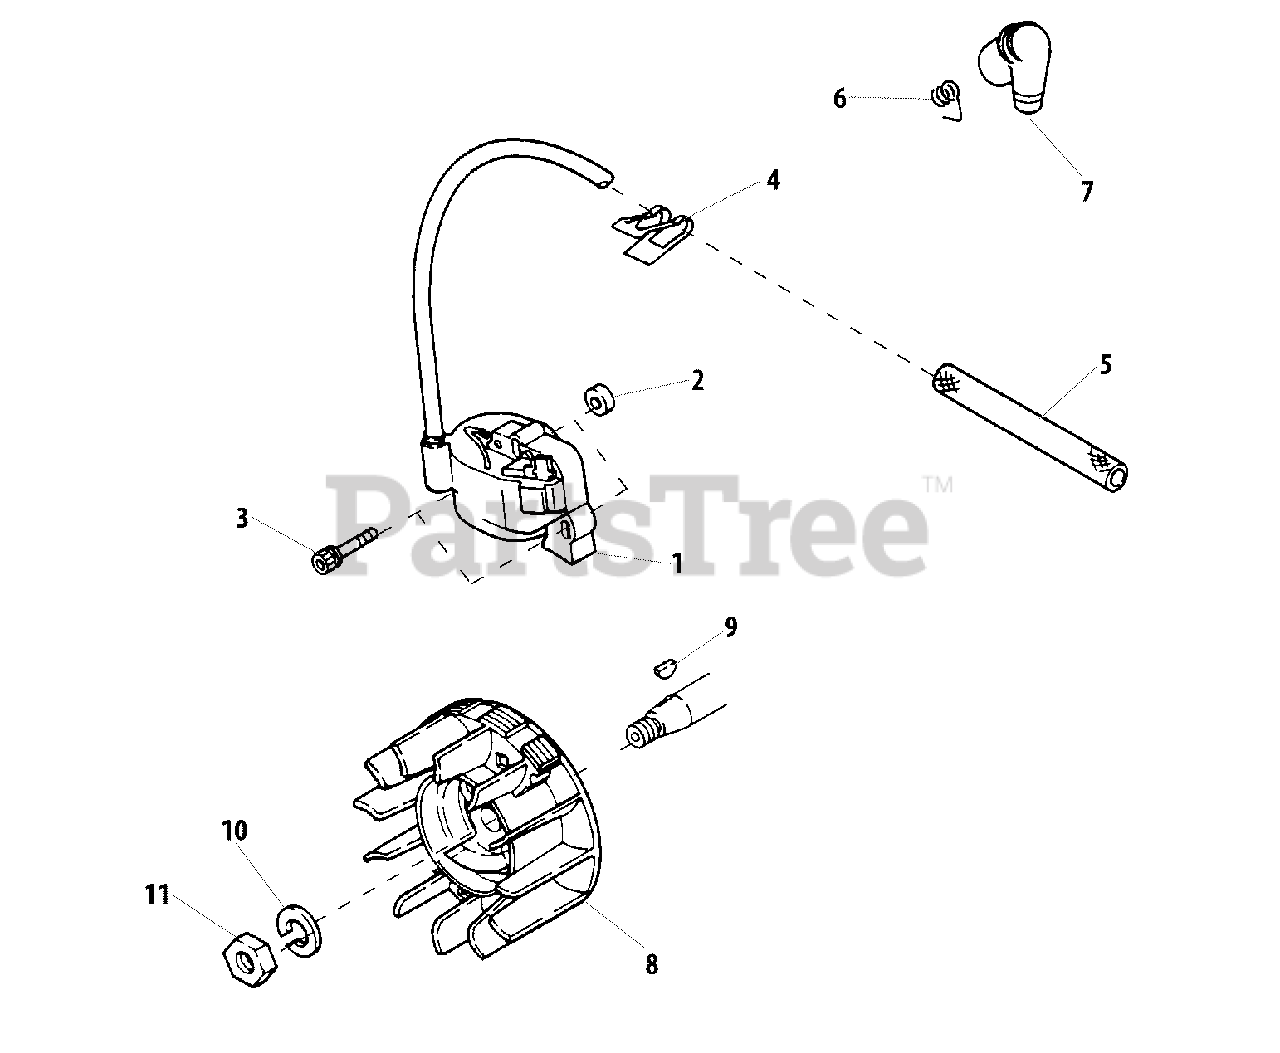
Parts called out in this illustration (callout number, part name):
1	COIL, IGNITION
2	INSULATOR
4	CLIP
5	TUBE, INSULATOR
6	TERMINAL, SPARK PLUG
7	CAP, SPARK PLUG
8	FLYWHEEL
9	KEY, WOODRUFF 3×10
10	WASHER, SPRING 8
11	NUT
